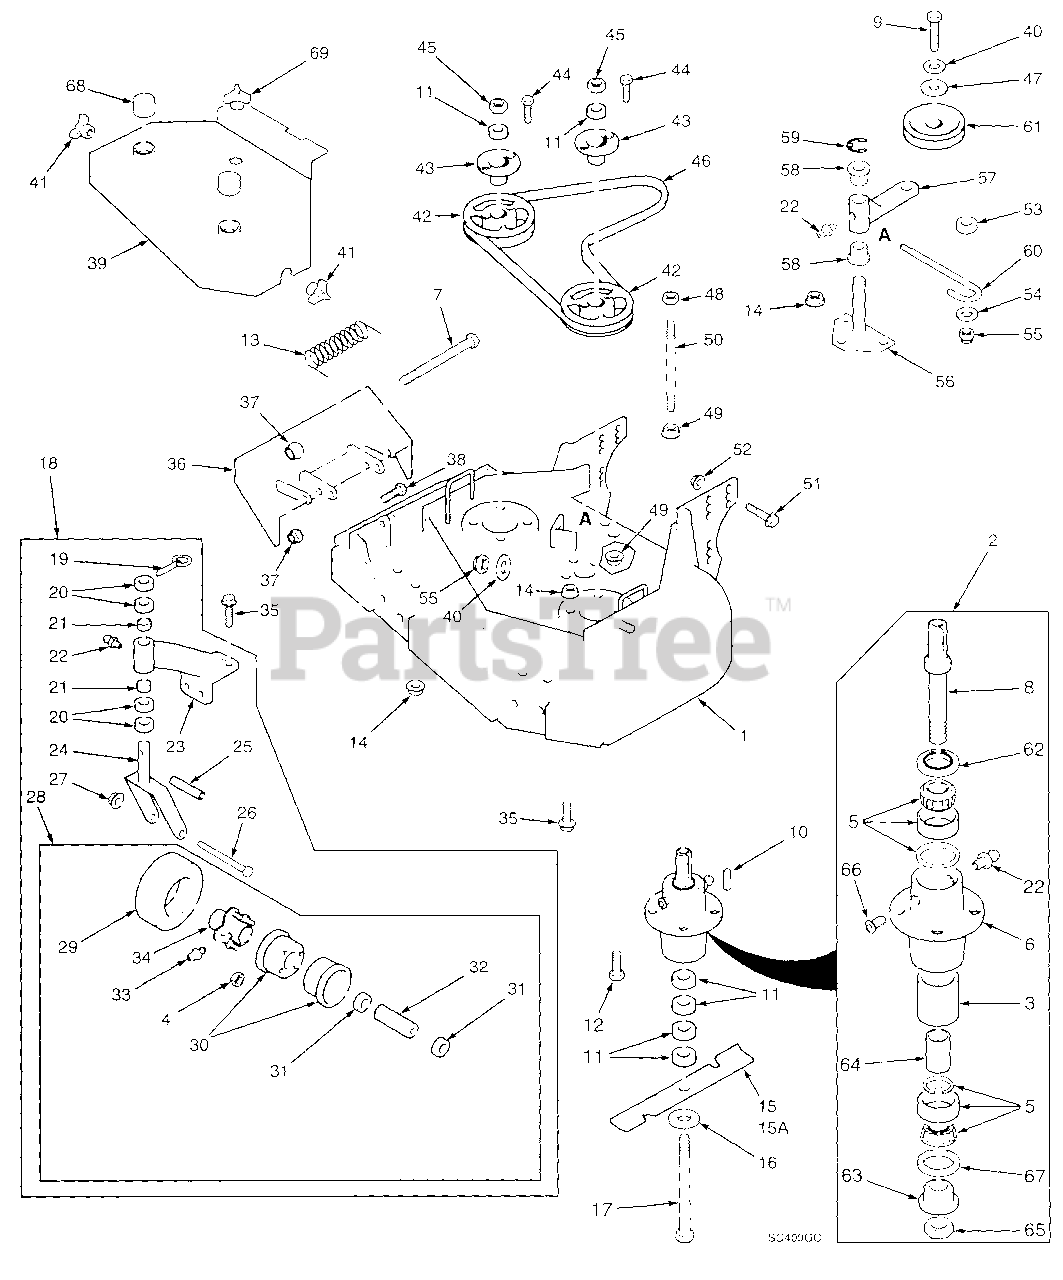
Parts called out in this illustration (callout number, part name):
1	Cutter Deck
2	Cutter Spindle Assembly
3	Spacer, Outside
4	Tapered Nut, 5/16-24
5	Tapered Bearing
6	Spindle Housing, Tapered Bearing
7	Bolt, 5/16-18 x 4-1/4" Hex Head
8	Spindle Shaft
9	Hex Head Bolt, 3/8-16 x 3-1/2"
10	Key, 1/4 x 2"
11	Spacer, Cutter Blade
12	Hex Head Bolt, 5/16-18 x 1-1/4"
13	Spring, Chute Return
14	Nut, 5/16-18 Serrated Flange
15	Cutter Blade, 18"
15A	Cutter Blade, 18" High Lift
16	Flat Washer, 5/8" W
17	Hex Hd. Bolt, 5/8-11 x 9-1/2"
18	Caster Assembly
19	Quick Pin
20	Spacer, Caster Yoke, 1/2" thick
21	Bronze Bearing
22	Grease Fitting
23	Support Assy.
24	Caster Yoke
25	Sleeve, Caster Wheel Bearing
26	Hex Hd. Bolt, 1/2-13 x 5-1/2"
27	Hex Locknut, 1/2-13
28	Wheel Assy.
29	Tire only, Caster Wheel
30	Rim Pair, Caster Wheel
31	Retainer, Bearing, Caster Wheel
32	Roller Bearing, Caster Wheel
33	Grease Fitting 45 deg., 1/4-28
34	Hub Assy.
35	Capscrew, 5/16-18 x 3/4" Serr. Flange Hex Head
36	Discharge Chute
37	Hex Nut, 5/16-18 Elastic Stop
38	Hex Head Bolt, 5/16-18 x 1"
39	Belt Cover Assembly
40	Flat Washer, 3/8" (.391 x .938 x .105)
41	Wing Nut, 3/8-16
42	Pulley
43	Tapered Hub, 1.125 Bore
44	Hex Head Bolt, 1/4-20 x 3/4"
45	Hex Nut, 5/8-11
46	Belt, Blade Drive
47	Spacer
48	Nut, Center Locknut - 3/8-16
49	Nut, 3/8-16 Serrated Flange
50	Support, Belt Cover
51	Capscrew, 7/16-14 x 1" Serr. Flange
52	Hex Nut, 7/16-14 Serrated Flange
53	Spacer, J-Hook
54	Flat Washer
55	Nut, 3/8-16 Elastic Stop
56	Idler Pivot
57	Idler Arm Assy.
58	Bushing, 1-1/8 x 1.0 Flanged
59	Retaining Ring, 1-1/8" Ext "E"
60	J-Hook
61	Idler Pulley, Belt Clutch
62	Seal, Cutter Spindle
63	Spindle Bushing
64	Spacer, Inside
66	Relief Fitting, Cutter Spindle
67	Seal, Cutter Spindle
68	Shield, Spindle
69	Wing Nut 3/8-16 (SM)
